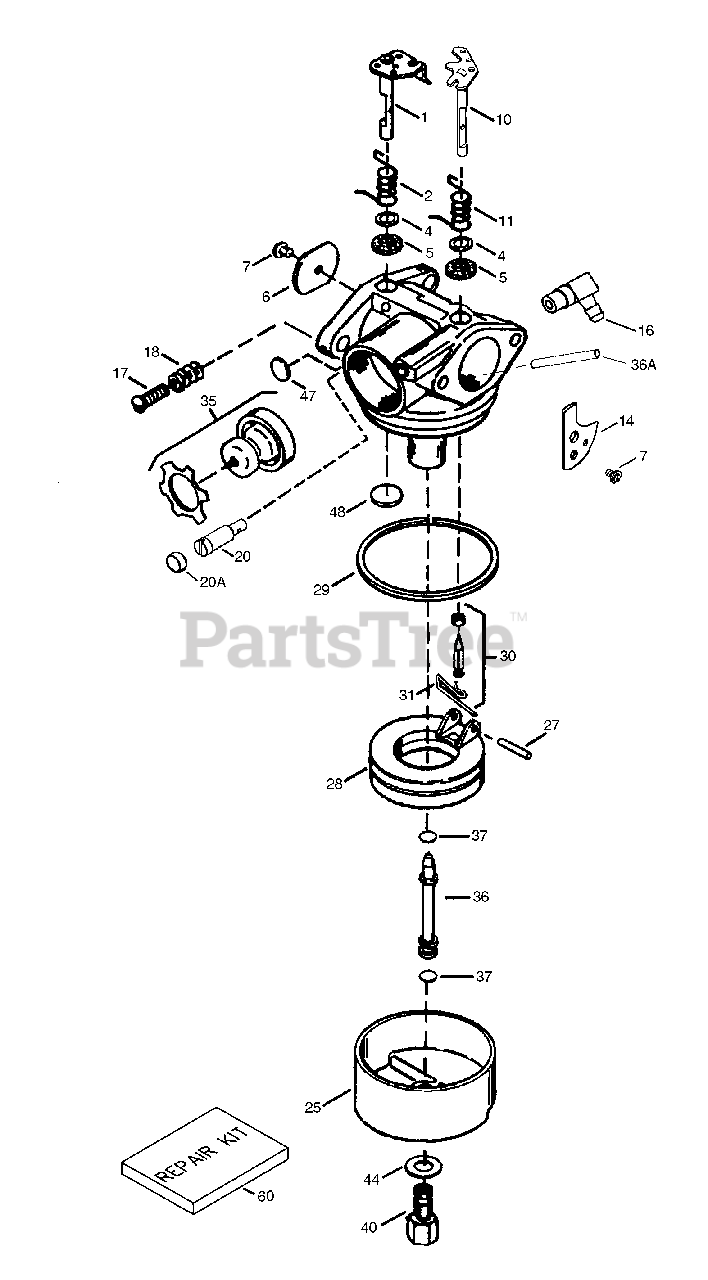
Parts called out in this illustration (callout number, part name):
1	Throttle Shaft & Lever Assembly
2	Throttle Return Spring
4	* Dust Seal Washer
5	* Dust Seal
6	Throttle Shutter
7	* Shutter Screw
10	Choke Shaft & Lever Assembly
11	Choke Return Spring
14	Choke Shutter
16	Fuel Fitting
17	Throttle Crack Screw/Idle Speed Screw
18	Tension Spring
20	Idle Restrictor Screw
20A	Idle Restrictor Screw Cap
25	Float Bowl
27	* Float Shaft
28	Float
29	* Float Bowl "O" Ring
30	* Inlet Needle, seat & Clip (Incl. 31)
31	Spring Clip
35	Primer Bulb/Retainer Ring
36	Main Nozzle Tube
37	* "O" Ring, Main Nozzle Tube
40	High Speed Bowl Nut
44	Bowl Nut Washer
47	* Welch Plug, Idle Mixture Well
48	* Welch Plug, Atmospheric Vent
60	Repair Kit (Incl. items marked PK in notes)
